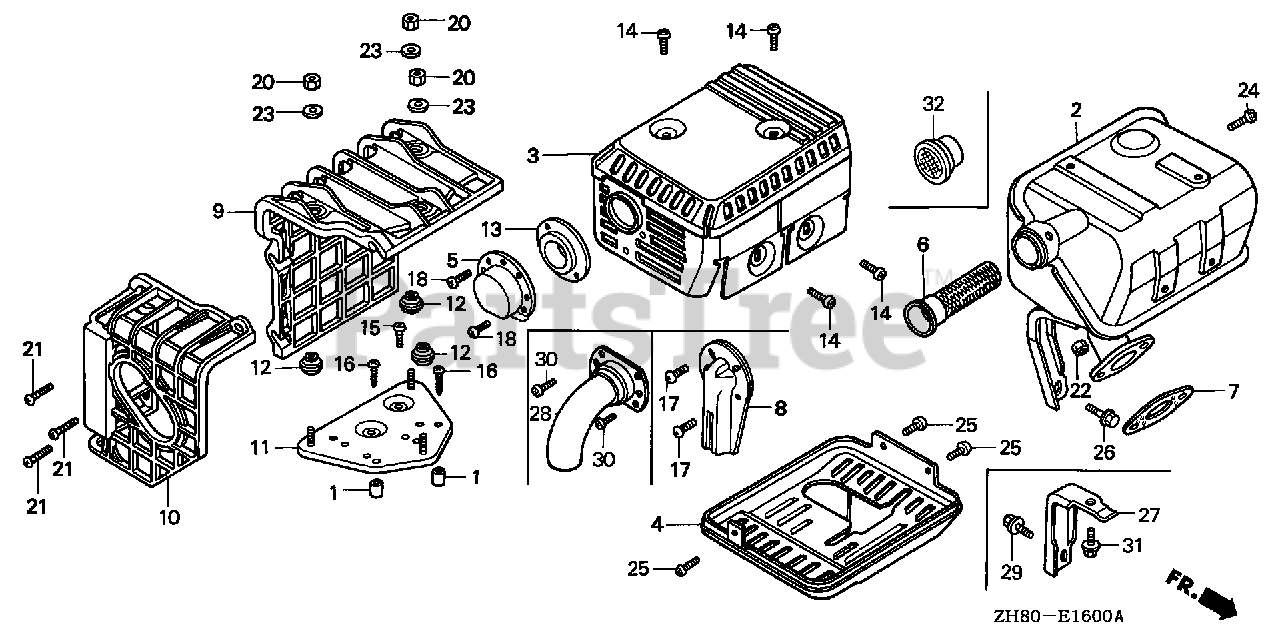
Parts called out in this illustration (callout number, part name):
2	MUFFLER (STD)
2	MUFFLER (ARRESTER)
3	PROTECTOR, MUFFLER (STD) (BLACK)
6	ARRESTER, SPARK
7	GASKET, MUFFLER
14	SCREW, TAPPING (5X8)
22	NUT, HEX. (8MM)
24	SCREW, TAPPING (4X6)
